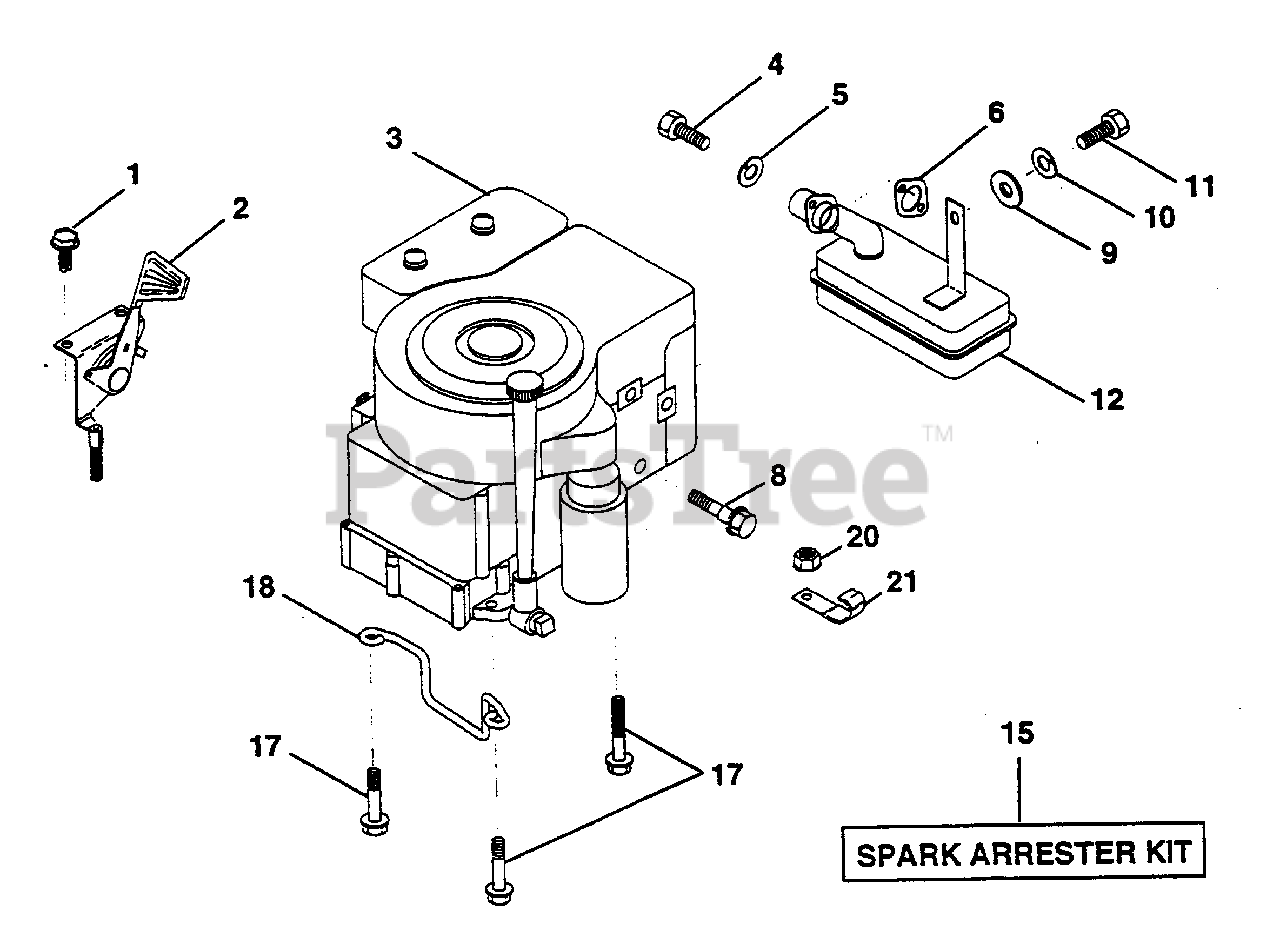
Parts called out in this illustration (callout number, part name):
1	Screw, Hex Head, Thread Cutting 1/4-20 x 1/2
2	Control, Throttle
4	Screw, Hex Cap Head 5/16-18 x 3/4
5	Washer, Lock, Heavy Helical Spring 5/16
6	Gasket, Exhaust
8	Bolt, Shoulder 5/16
9	Washer 5/16 x 3/4 x 16
10	Washer, Lock, Heavy Helical Spring 1/4
15	Arrester, Spark (Optional Equipment)
17	Screw, Hex Washer Head, Thd., Roll. 3/8-16 x 1-1/2
18	Keeper, Ground Drive Belt
20	Nut, Hex, Keps 3/8-16
21	Clip, Fuel Line
